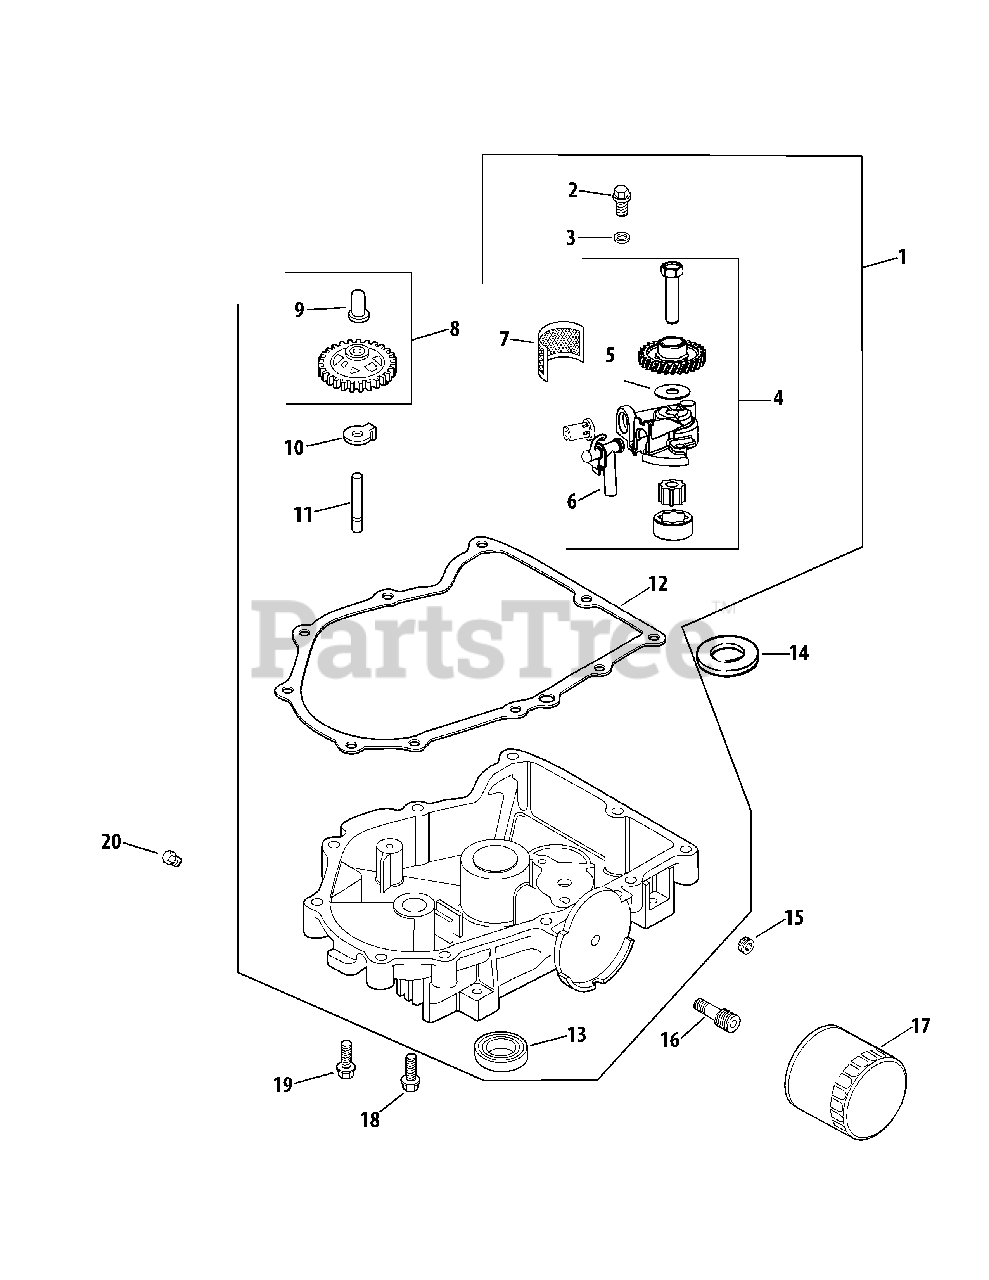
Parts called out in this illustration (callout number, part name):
1	Oil Pan Assembly Kit (Inc. 2-10)
2	Screw
4	Oil Pump Assembly Kit (Inc. 5 & 6)
6	Oil Pick-Up Tube (CV)
8	Governor Gear Kit w/ Pin (Inc. 9)
12	Oil Pan Gasket
16	Oil Filter Nipple
18	Hex Flange Screw
19	Hex Flange Screw
